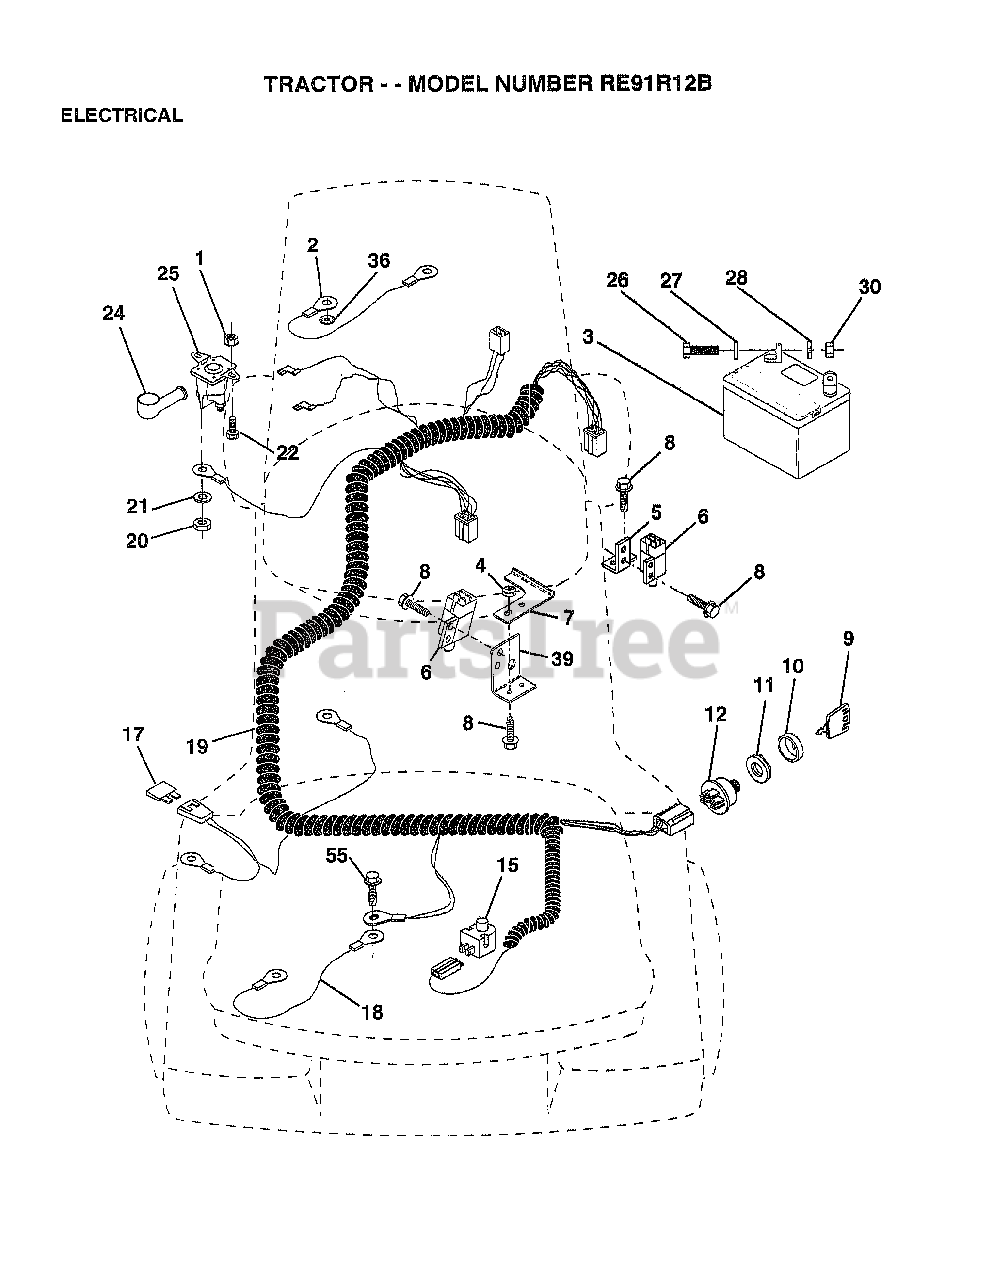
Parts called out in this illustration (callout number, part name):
1	NUT HXKEP 1/4X20
4	LOCKNUT
5	BRACKET LT
6	SWITCH INTERLOCKT
7	KEEPER.ACTUAT.LR.
8	SCREW
9	KEY STEEL DELTA
10	COVER KEY SWITCH
12	SWITCH.IGNITION
15	SWITCH SEAT
17	FUSE HYT
18	CABLE ASSY
19	HARNESS.IGN.FEND.
20	NUT
22	BOLT HXHD FIN
26	BOLT LT
27	WASHER
28	LOCKWASHER
36	LOCKWASHER
39	BRACKET SWT CLUTC
55	SCREW LT
